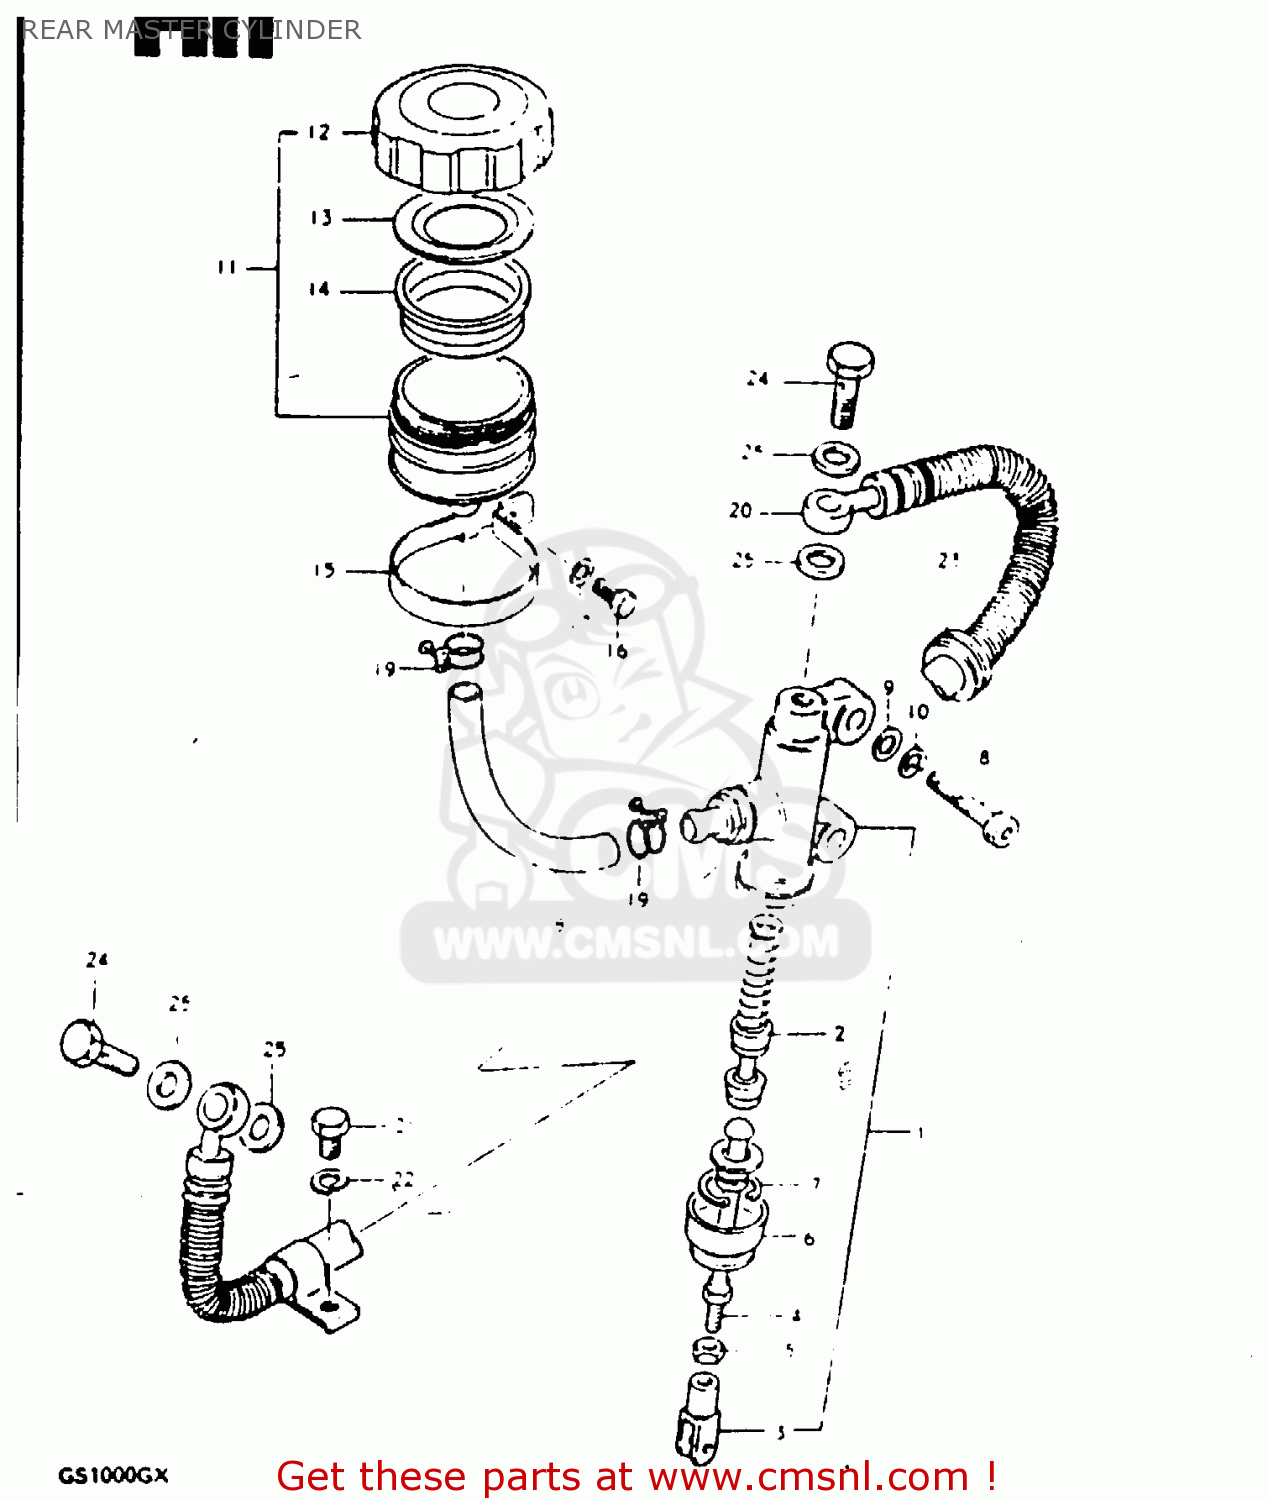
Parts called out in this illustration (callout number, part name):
1	CYLINDER ASSEMBLY,REAR MASTER
2	PISTON/CUP SET
3	YOKE
4	ROD,PUSH
5	NUT
6	BOOT
7	CIRCLIP
8	BOLT
9	WASHER
10	WASHER,LOCK,8.
11	TANK ASSEMBLY,RESERVOIR
12	CAP
13	PLATE,DIAPHRAGM
14	DIAPHRAGM
15	CLAMP
16	BOLT, UPPER
17	LOCK WASHER
18	HOSE,RESERVOIR TANK
19	CLAMP
20	HOSE,REAR BRAKE
21	BOLT
22	LOCK WASHER
23	GROMMET
24	BOLT,UNION
25	WASHER
